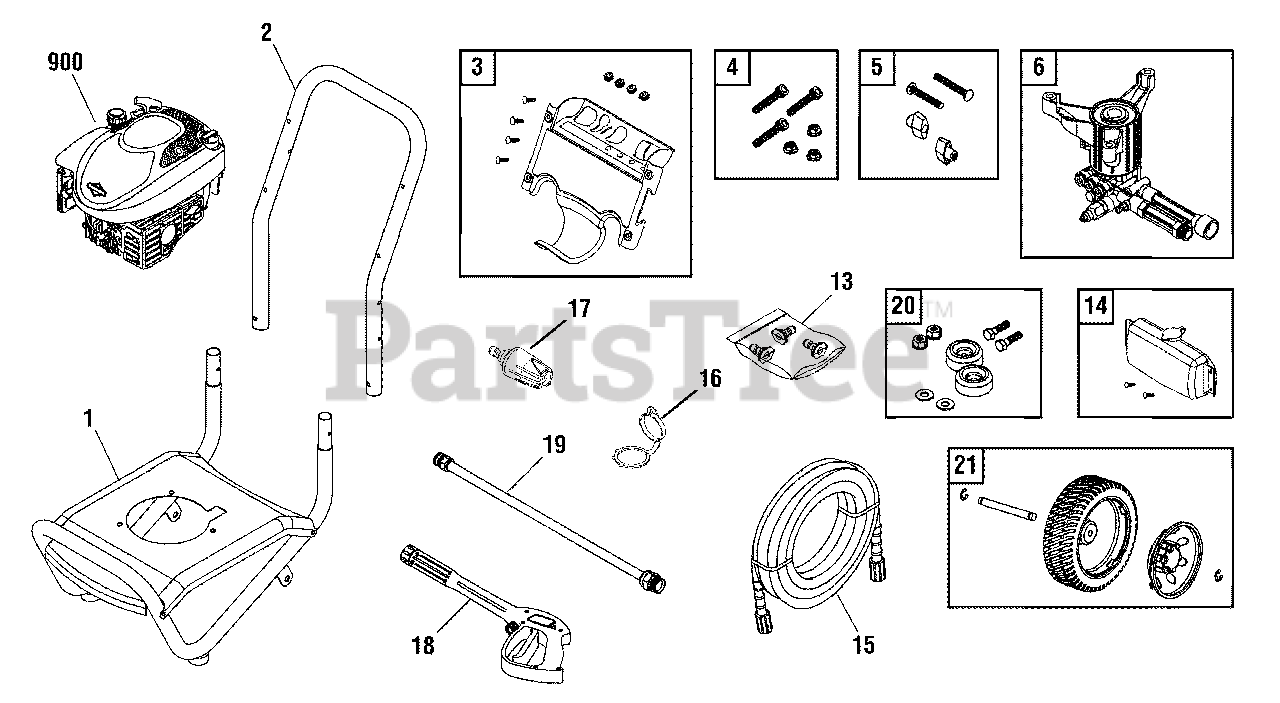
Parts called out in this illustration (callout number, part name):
2	HANDLE
3	KIT, Billboard Assy, w/Decals & Clips
4	KIT, Hardware, Pump
5	KIT, Hardware, Handle
6	PUMP
13	KIT, Nozzles
16	CAP, Chemical Container
17	TURBO MAX
18	GUN
19	EXTENSION
20	KIT, Vibration Mount
900	* ENGINE
